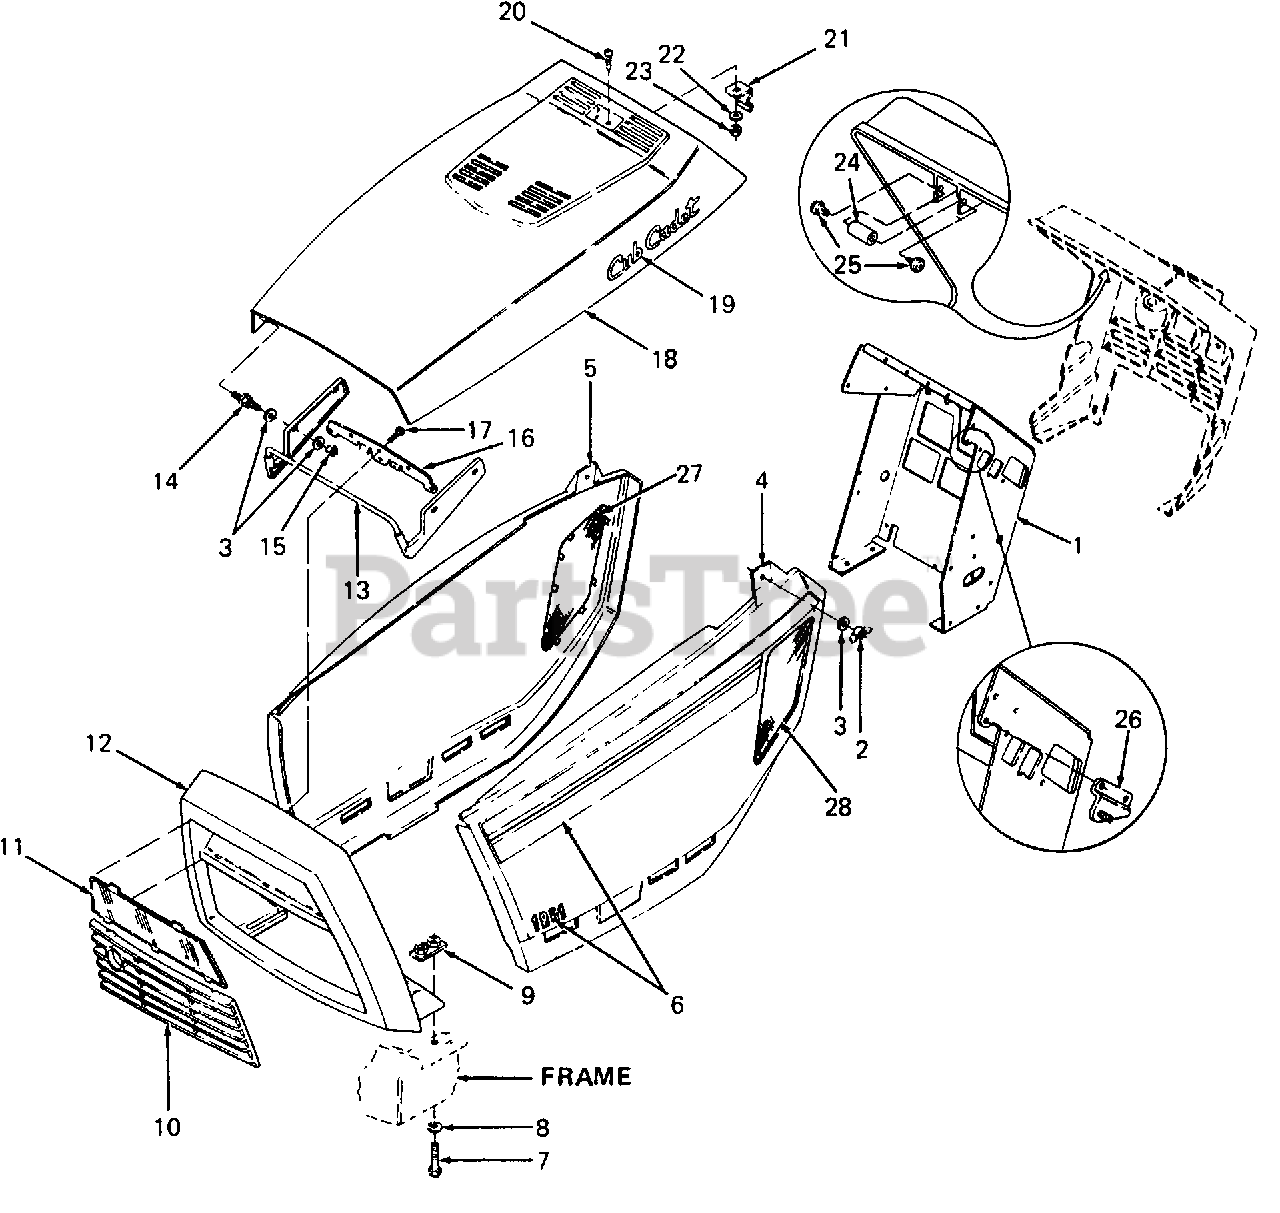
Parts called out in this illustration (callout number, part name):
3	Washer, Flat, .251 X .62 X .052 Thk
4	Panel, LH Side
5	Panel, RH Side
6	Graphics Kit, LH Side Panel
7	Screw, Hex Cap, 5/16-18 X 1.0 Lg GR5
8	Washer, Lock, 5/16
9	Retainer, Grille Housing
10	Grille, Insert
11	Grille, Lens
12	Grille w/Label
15	Nut, Hex Patch Lock, 1/4-20
18	Hood
19	Graphic, Cub Cadet Script w/Studs
20	Screw, Truss Hd, #8-32 X .38 Lg
21	Clip, Hood Latch
22	Washer, Flat, .16 X .38 X .045 Thk
23	Nut, Hex Keps, #8-32
24	Pin, Latch
25	Screw, Phillips Hd Truss Mach, 1/4-20 X .50 Lg
